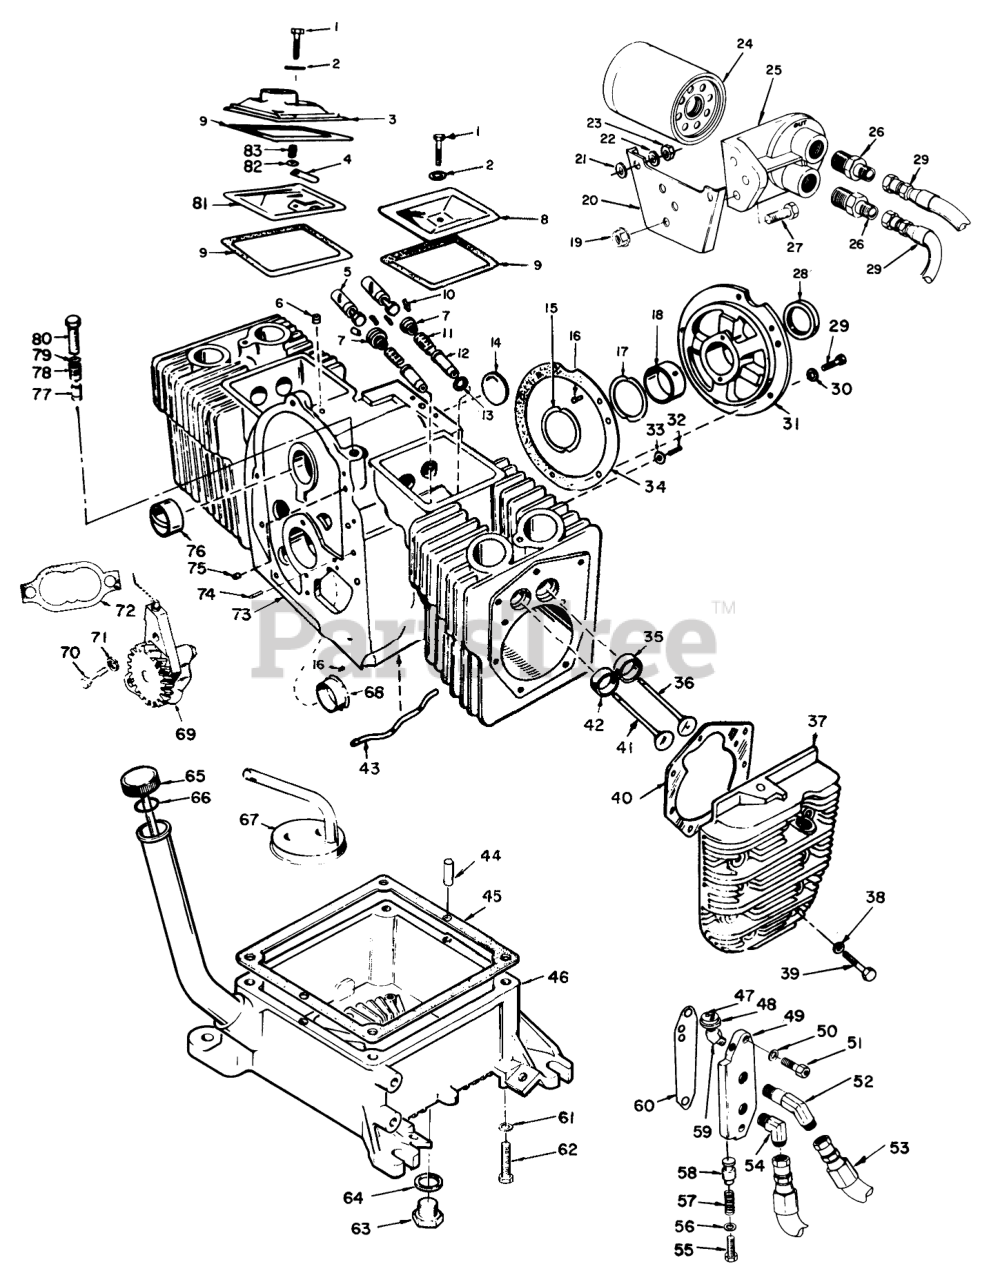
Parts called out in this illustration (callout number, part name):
1	Screw-Cap Hex Hd.
2	Washer, Flat-Copper
3	Cover-Valve
4	Reed-Breather Valve
5	Tappet, Valve (Standard)
6	Plug, Breather Hole
7	HYD MOTOR ASM
8	RH LEVER / GRIP ASM
9	Gasket, Valve Cover
10	Lock, Valve Spring
11	Spring Valve
12	Guide, Valve
13	Gasket, Intake Valve Guide
14	Plug, Welch-Camshaft Opening
15	Washer-Thrust
16	Pin, Drive-Bearing stop
17	Shim, Crankshaft End Play (.005)
18	Bearing, Crankshaft Rear Standard (Incl. Ref. #15)
19	Nut, Self-Lock
20	Bracket, Remote Oil Filter
21	Washer, Over Bracket
22	Washer, Under Bracket
23	Nut, Hex
24	Filter Oil
25	Base, Remote Oil Filter
26	Connector, Male
27	Screw Cap-Hex Hd.
28	Seal, Oil-Crankshaft Rear
29	Screw Cap-Hex Hd.
30	Washer, Lock-Spring
31	Plate, Bearing-Rear
33	Washer, Flat
34	Gasket, Bearing Plate
35	Insert, Valve Seat-Intake (Standard)
36	BRUSH-SCRAPER, WIDE (18 INCH)
37	LEVER-ACTUATING
38	Washer, Flat
39	Screw, Cap-Hex Head (Special)(5/16-18x 1-5/8")
40	SPACER
41	Valve Exhaust
42	GAS-LINE
43	Tube, Oil-Cylinder Block
44	Pin Dowel-Oil Base
45	Gasket, Oil Base
46	Base, Oil
47	Lead, Low Oil Pressure Cut Off
48	Switch, Low Oil Pressure Cut Off
49	Adapter, Oil Filter
50	Washer, Flat Copper
51	Screw, Cap-Socket Head
52	Elbow, Male (To Filter)
53	Hose, Oil
54	Elbow, Male (From Filter)
55	Screw, Cap Hex Hd.
56	Washer, Flat
57	Spring, By-Pass
58	Plunger, Bypass Valve
59	Elbow, Street 45 Deg.
60	Gasket, Oil Filter Adapter
61	Washer, Lock-Spring
62	Screw, Cap-Hex Head
63	Plug, Oil Drain
64	Gasket, Oil Drain
65	Cap and Indicator,Oil Fill
66	O-Ring, Oil Fill Cap
67	Cup, Intake-Oil Pump
68	Bearing, Crankshaft-Front(Flanged) Standard
69	Pump, Oil
70	Screw, Cap-Hex Hd.
71	Washer, Lock
72	Gasket Kit, Oil Pump
73	Block Assy. (Incl. Ref. #6, 12-18, 29-31, 34-35, 42-43, 68, 74 & 76)
74	Pin, Gear Cover Alignment
75	Plug,Core Hole
76	Bearing, Camshaft
77	Plunger, Bypass Valve
78	Spring, Bypass Valve
79	Washer, Flat-Copper
80	Screw, Cap-Hex Head
81	Baffle, Breather Valve
82	Washer, Flat
83	Spring, Breather Valve
